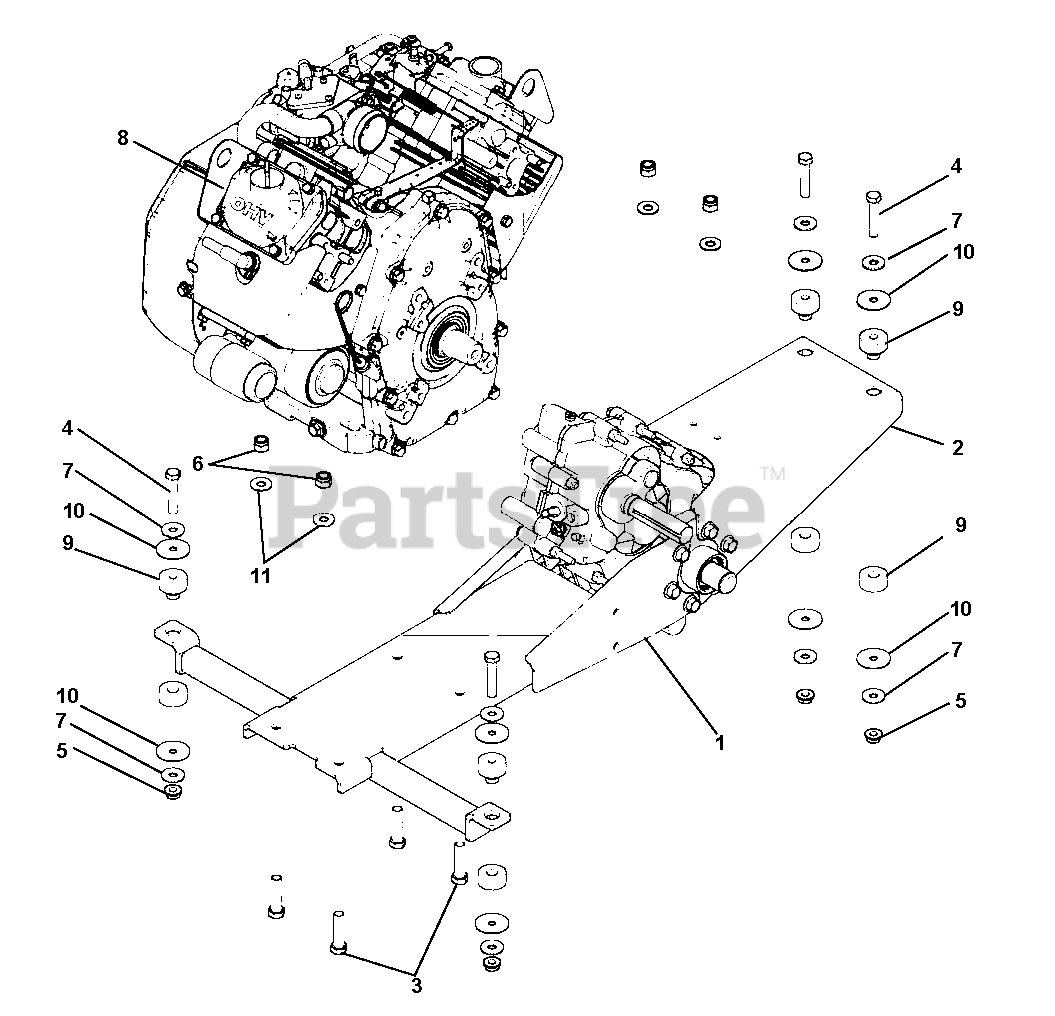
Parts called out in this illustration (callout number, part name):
1	ENGINE MOUNT WELDMENT
2	TRANS MNT SUPPORT BRACKET ST
3	BOLT, HEX .44-14 X 1.75 GR5 YWZC
4	BOLT, HEX .38-16 X 2.00 GR5 YWZC
5	NUT, LOCKING TOP FLANGE .38-16 YWZC
6	NUT, LOCKING TOP .437-14 GR C PL
7	WASHER, FLAT STEEL .438 X 1.00 X .083 YWZ
8	ENGINE, SUBARU, EH65
9	MOUNT MOTOR H SYTLE
10	WASHER, FLAT STEEL .402 X 2.00 X .055 YWZ
11	WASHER, FLAT STEEL .531 X 1.06 X .095 YWZC
